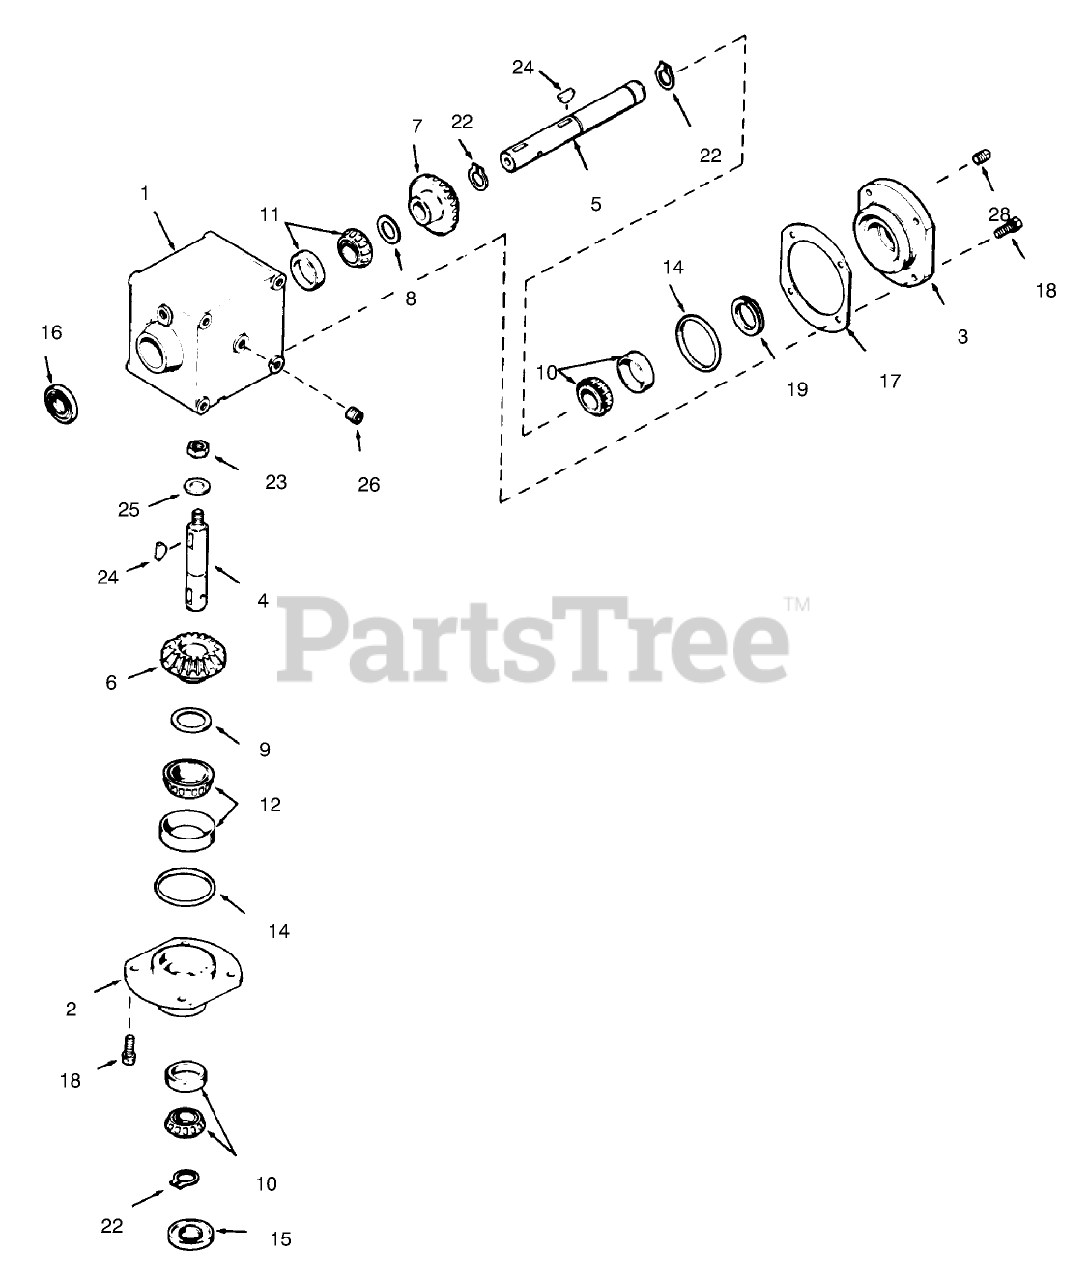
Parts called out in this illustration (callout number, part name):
1	Housing
2	Cap-Retainer
3	Cap-Retainer
4	Shaft-Input
5	Shaft-Output
6	Gear-Bevel 25T
7	Gear-Bevel 26T
8	Shim (1.5" OD x 1.016" ID x .002")
9	Shim (2" OD x 1.531" ID x .002")
10	Bearing Cup Assembly
11	Bearing Cup Assembly
12	Bearing Cup Assembly
14	ORing
15	Seal-Oil
16	Seal-Oil
17	Shim-Oil
18	Screw-Hex Hd.
19	Ring-Load
22	Ring-Retaining
23	Jam Nut
24	Key-Woodruff
25	Washer-Flat
26	Plug-Pipe
28	Plug-Pipe
